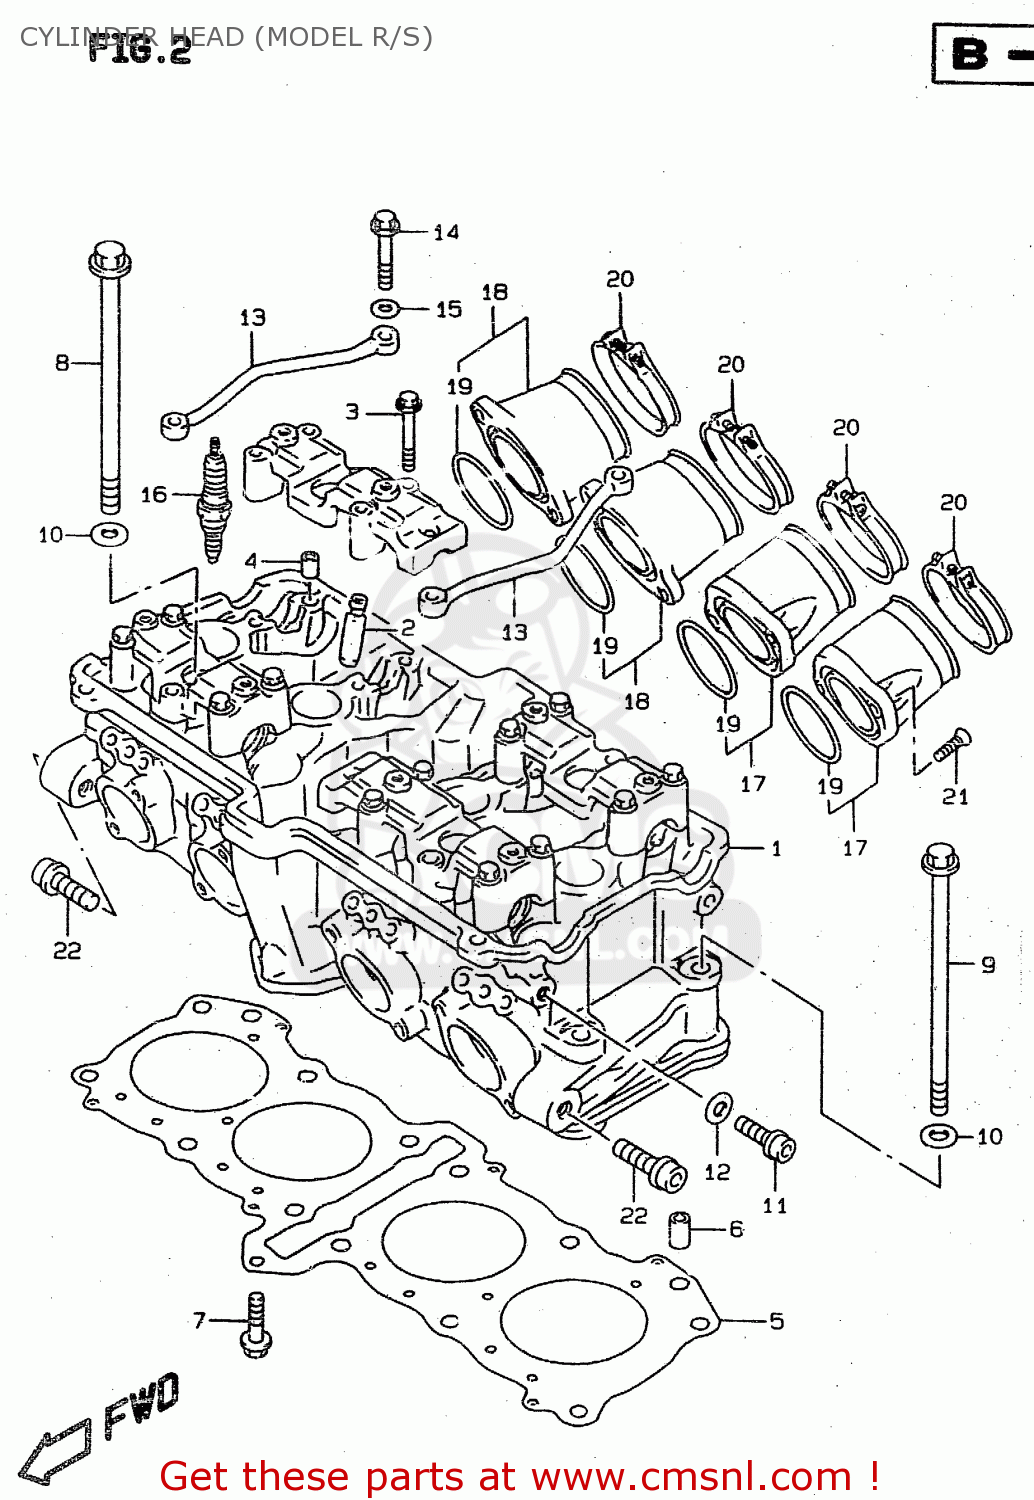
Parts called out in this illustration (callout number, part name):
1	HEAD ASSEMBLY,CYLINDER
2	GUIDE,VALVE
3	BOLT(6X45)
4	PIN(6.2X8X11)
5	GASKET,CYLINDER HEAD
6	PIN
7	BOLT
8	BOLT 10X175
9	BOLT(10X175)
10	WASHER(10.5X19X2)
11	BOLT
12	GASKET(8.2X14X1).6 (NAS)
13	PIPE,CYLINDER HEAD OIL
14	BOLT(6X39)
15	WASHER
16	PLUG,SPARK(CR8E)
17	PIPE, INTAKE NO. 1
18	PIPE, INTAKE NO. 2
19	O RING(D:2.4,ID:41.7)
20	CLAMP
21	SCREW(6X16)
22	BOLT
